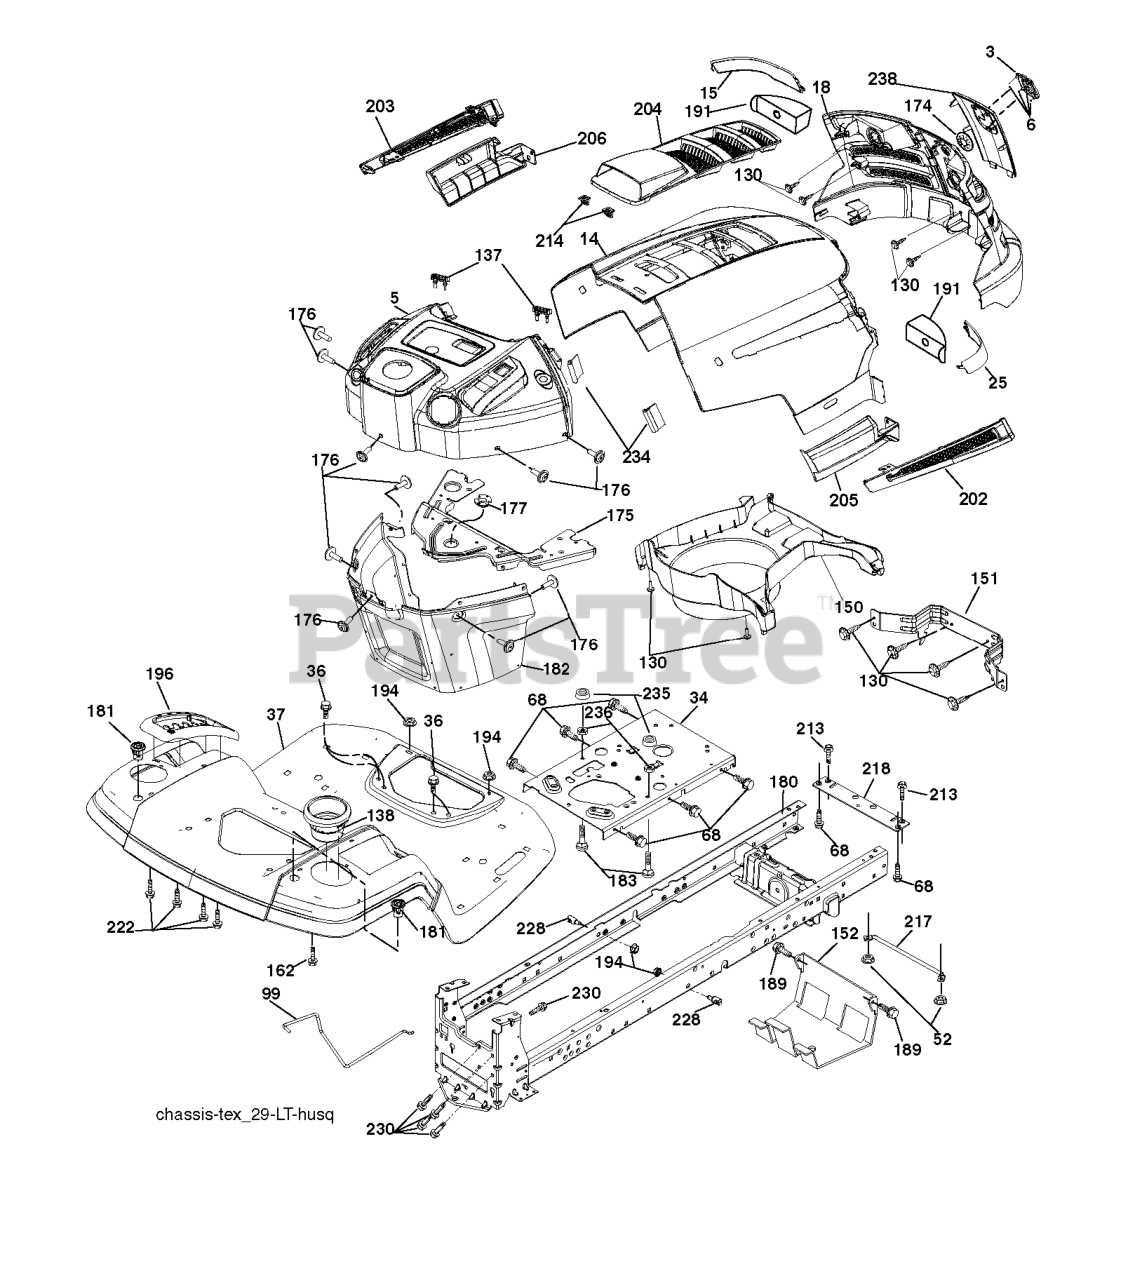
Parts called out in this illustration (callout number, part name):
3	RP LOGO
14	HOOD
15	LENS.HUSQVARNA LT.LH
18	RP GRILLE/LENS ASM.
25	LENS.HUSQVARNA LT.RH
34	PLATE.ENGINE.WELDED.CHASSIS
36	SCREW 5/16"
37	FEND/FTRST.PCH.CPH.NFW
52	LOCKNUT
68	Screw 5/16-18 x 1/2 Hex, Self Tapping 5/16-18 x 1/2
99	ROD ASM BYPASS
130	SCREW
137	BUMPER DASH
138	CUPHOLDER.TL.TEX.418
151	BRACKET PIVOT
152	SHIELD.BROWNING.W/TEX
162	SCREW.HI-LO.CONSOLE
175	CROSSMEMBER
176	SCREW.#10-24X5/8.RN.QU
177	BUSHING STEERING
180	CHASSIS
181	BUSHING.MNT.FEND.CRGO.
182	DASH LOWER
183	BOLT.5/16-18X1-1/4 FULL.THREAD
189	SCREW
191	INSERT REFLECTIVE
194	NUT LOCK HEX FLANGE 5/16-18
196	CONSOLE.ASM.DECK.LIFT.
202	VENT SIDE HOOD RH
203	VENT SIDE HOOD LH
204	VENT TOP HOOD
205	SKIRT SIDE RH
206	SKIRT SIDE LH
213	BOLT
214	CLIP.RETAINER.TINNER.
217	ROD PIVOT CHASSIS/HOOD
218	X-PIECE.HOOD.STOP.NON/
222	SCREW.1/4-20X5/8
228	STUD.FASTNER.W/ANTI-ROTATE
230	SHOULDER BOLT 5/16-18TT
234	BUMPER.HOOD.TEX.HUSQVARNA
235	SPACER FENDER
238	TRIM
